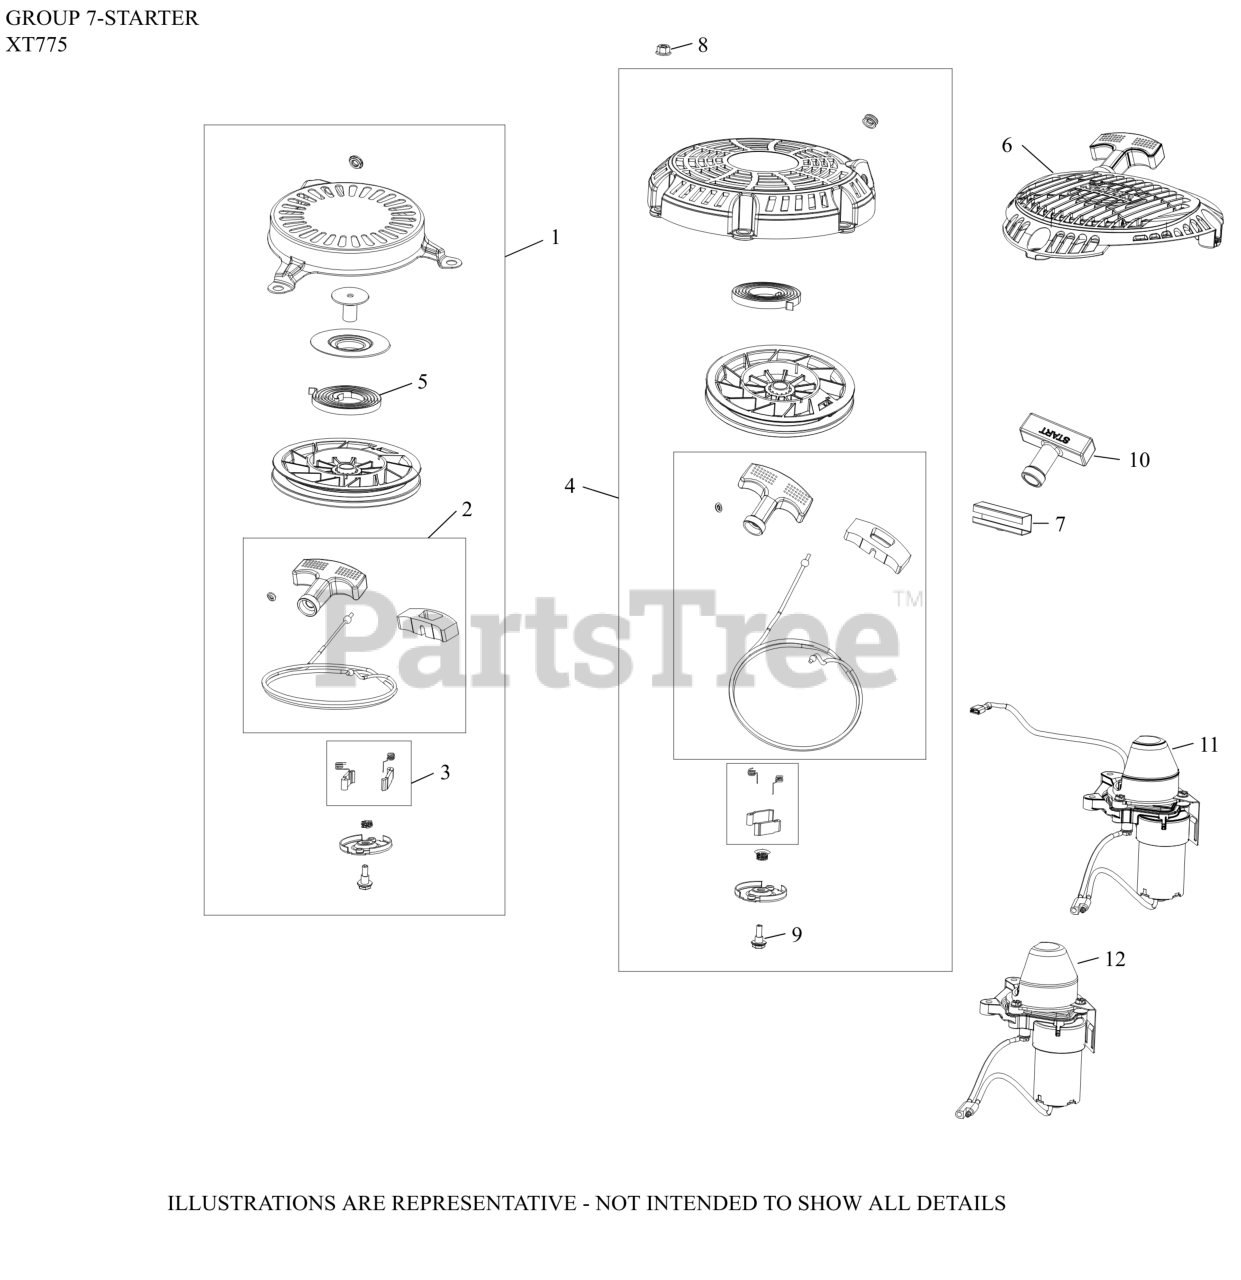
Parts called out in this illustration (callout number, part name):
1	STARTER ASSEMBLY, RETRACTABLE
2	KIT, STARTER ROPE W/HANDLE
3	KIT, PAWL REPAIR
